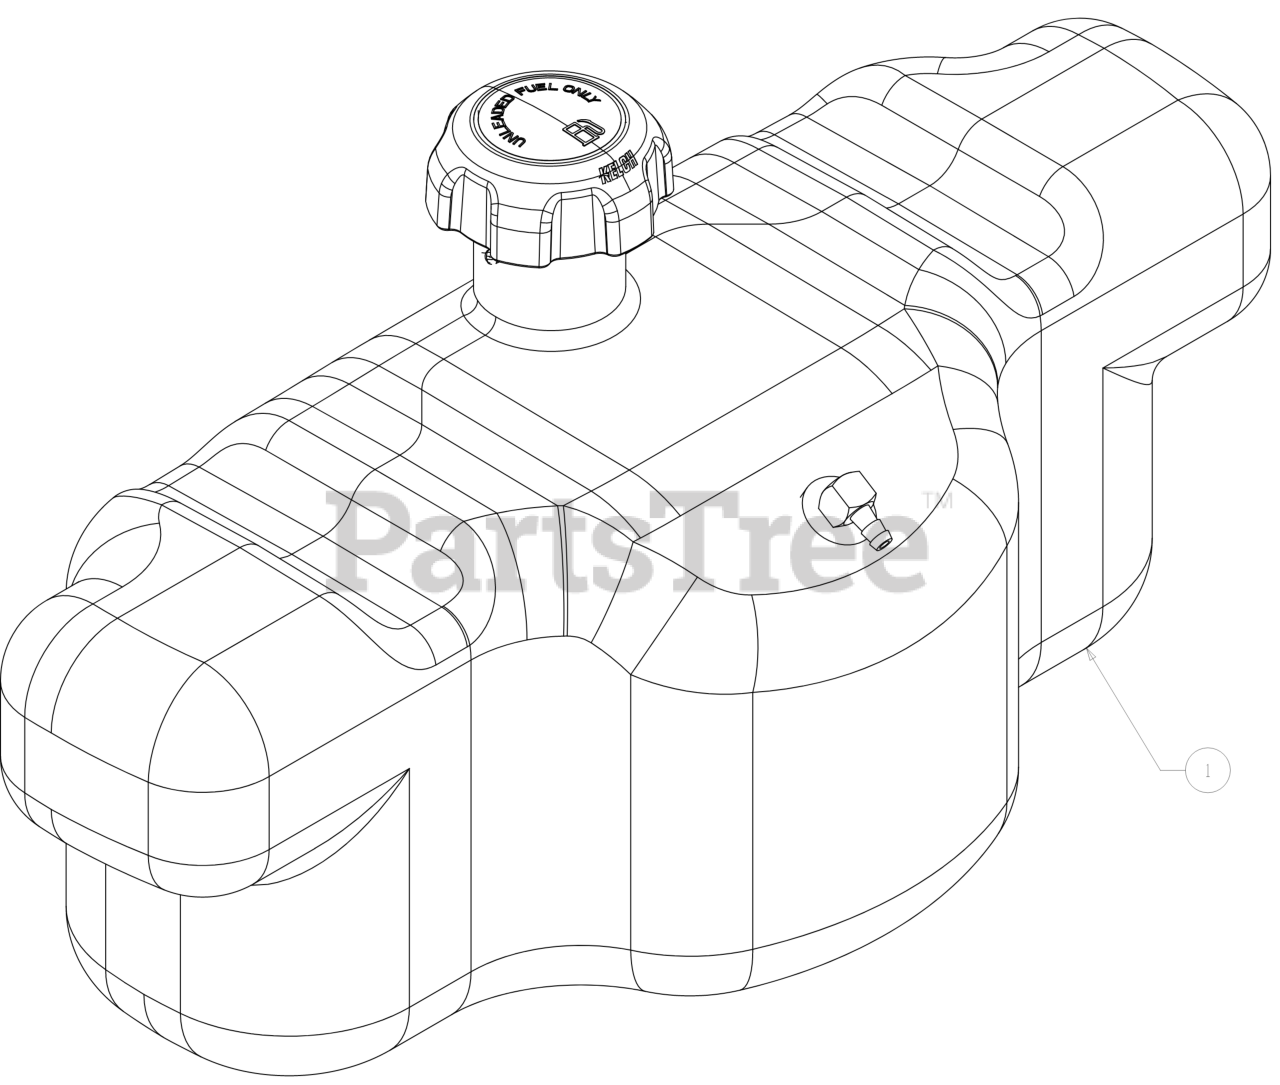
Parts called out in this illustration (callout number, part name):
1	FUEL TANK ASSEMBLY W/CAP
1	BUSHING
1	FUEL PICKUP FITTING
1	FUEL CAP W/TETHER
